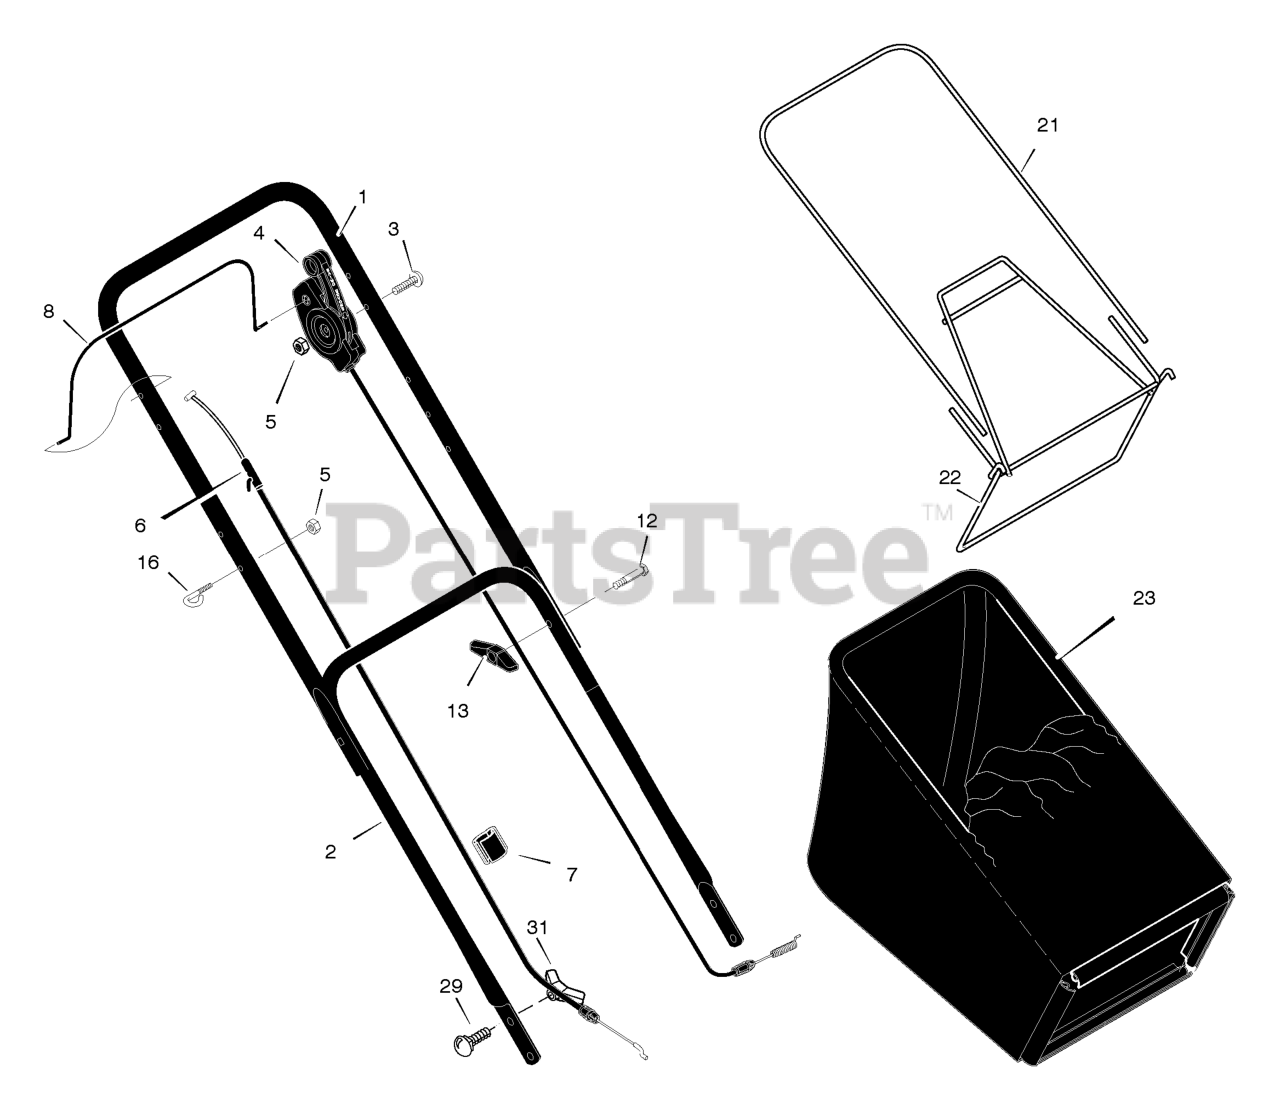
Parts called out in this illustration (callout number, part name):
1	Handle, Upper (Black)
2	Handle, Lower (Black)
4	Control, Drive
5	Locknut
6	Cable, Stop
7	Fastener, Cable
8	Lever, Stop
13	Knob
16	Guide, Rope
21	Frame, Top
22	Frame Assembly
23	Bag, Cloth
29	Bolt, Carriage
31	Knob, Plastic
